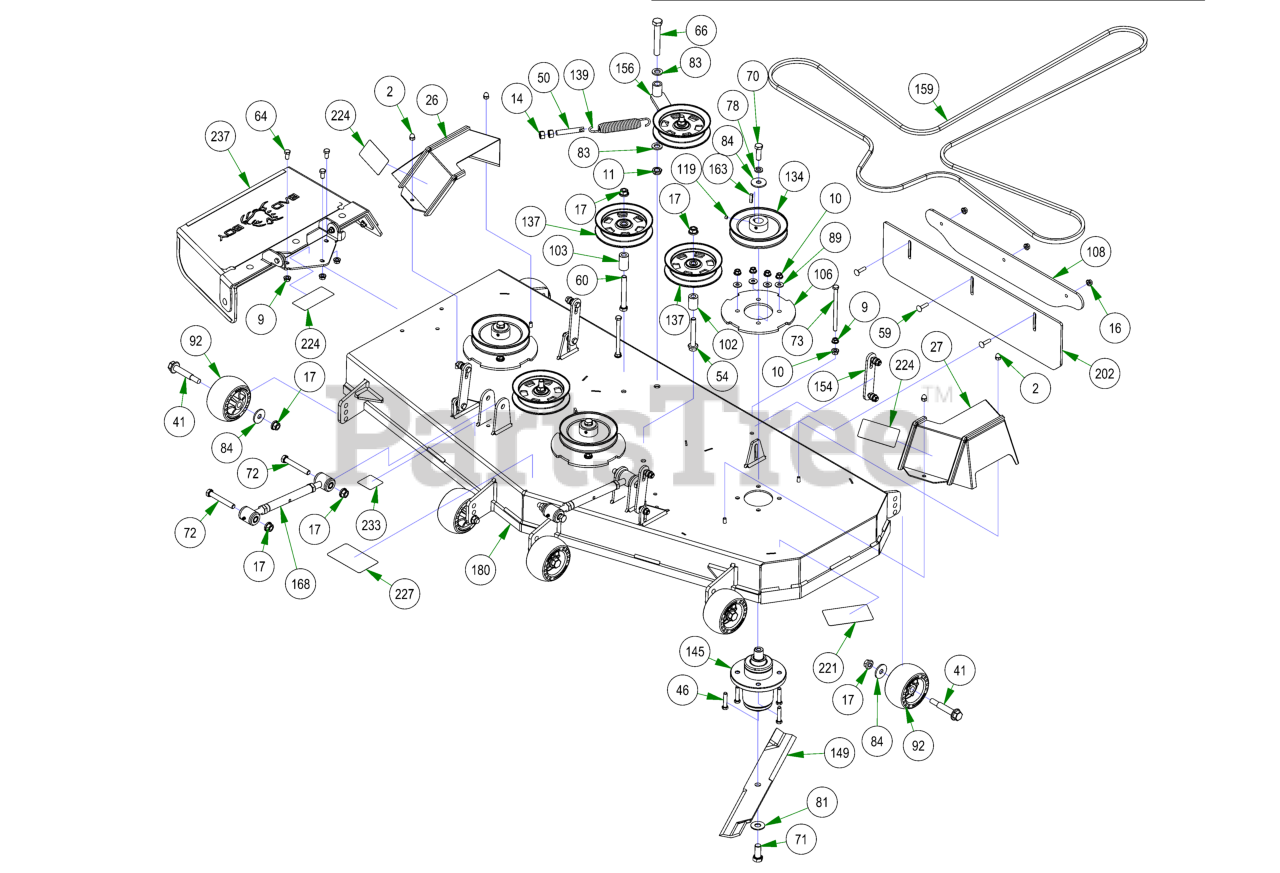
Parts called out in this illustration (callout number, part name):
2	5/16-18 ACORN NUT HIGH-CROWN ZC
9	3/8-16 HEX SERRATED FLANGE NUT HARD/ZINC
10	3/8-16 NYLON INSERT FLANGE LOCKNUT (GR.F) ZINC
11	5/8-11 NYLON INSERT JAM LOCKNUT ZINC
14	1/2-13 HEX NUT ZINC
16	5/16-18 NYLON INSERT FLANGE LOCKNUT ZINC
17	1/2-13 NYLON INSERT FLANGE LOCKNUT ZINC
26	2021 Maverick 54”/60” RH Pulley Cover
27	2021 Maverick 54”/60” LH Pulley Cover
41	Deck Wheel Bolt
46	3/8-16 X 1-3/4 HEX C/S (GR.5) ZC
50	All Thread
54	1/2-13 X 3-1/2 HEX FLANGE BOLT (GR.8) ZINC
59	5/16-18 X 1-1/4 CARRIAGE BOLT ZINC
60	1/2-13 X 4 HEX CAP SCREW (GR.8) ZINC YELLOW
64	3/8-16 X 3/4 HEX CAP SCREW (GR.5) ZINC
66	5/8-11 X 4 HEX CAP SCREW (GR.8) ZINC YELLOW
70	1/2-20 X 1-1/2 HEX CAP SCREW (GR.5) ZINC
71	5/8-18 X 1-1/2 HEX CAP SCREW (GR.8) ZINC YELLOW
72	1/2-13 X 3-1/2 HEX CAP SCREW (GR.5) ZINC
73	3/8-16 X 5-1/2 HEX CAP SCREW (GR.5) ZINC
78	1/2 SPLIT LOCKWASHER (GR.8) ZINC/YELLOW
81	5/8 USS FLAT WASHER (1-3/4" OD) GR.8 ZINC YELLOW
83	.635 ID X 1.120 OD X .140 THICK FLAT WASHER NYLON
84	1/2 BELLEVILLE WASHER (1-5/8 OD X .140 THK) ZINC
89	5/16 USS FLAT WASHER (7/8 OD) ZINC
92	Deck Wheel
102	.502 ID X .750 OD X 1.500 Long Spacer
103	1 3/4" Pulley Spacer
106	Deck Spindle Support Plate
108	2023 4" & 5" Stripping Kit Plate
119	5/16-24 X 1/4 SOCKET SET SCREW (CUP PT) PLAIN
134	6 1/4" Drive Pulley
137	5-3/4 Idler Pulley
139	Deck Idler Spring
145	OUTLAW SPINDLE ASSEMBLY
149	60" High Lift Fusion Blade
154	Deck Hanger Assembly
156	2017 MZ/ZT Deck Idler Assembly
163	1/4 X 1 SQ MACHINERY KEY 1018 STL PLN
168	2018 Maverick Turnbuckle (Top Link)
180	2023 60" x 5" Deck
202	2023 ZT Stripping Kit Rubber
221	2018 60" Deck Decal
224	Danger Decal-Spindle/Discharge
227	Deck Belt Route Decal
233	Deck Impact Patent Decal 9591803
237	Discharge Chute Assembly
